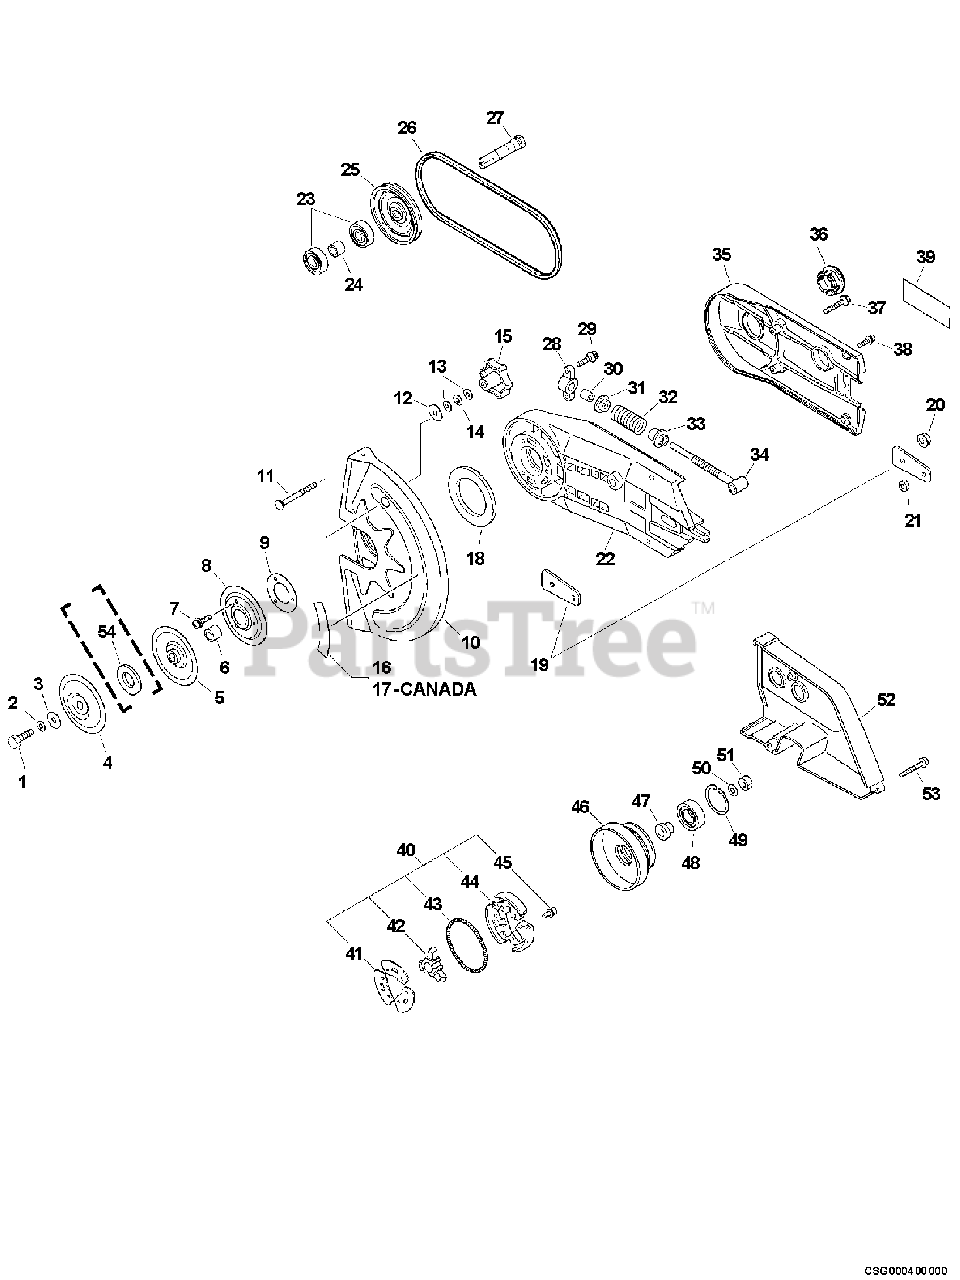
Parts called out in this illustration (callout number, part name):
1	BOLT - 10
2	LOCKWASHER - 10
4	FLANGE, CUTTER
5	FLANGE, CUTTER
7	SCREW - 4X10
8	PLATE, CUTTER COVER
10	COVER, BLADE
11	BOLT - 10X70
13	WASHER - 10
14	LOCKWASHER - 10
16	LABEL - CAUTION
19	SPACER, ARM
20	NUT - FLANGE
21	WASHER - 8
22	COVER, V-BELT
23	BEARING, BALL - 6203
24	SPACER
28	SUPPORT
29	SCREW - 5X20
30	SPACER, SHAFT
31	SEAT, SPRING
32	SPRING, ADJUST
33	ADJUSTER
34	ROD, ADJUST
35	COVER, ARM - FRONT
37	SCREW - 5X25
38	SCREW - 5X20
39	LABEL - ECHO
40	CLUTCH ASSY
41	PLATE, CLUTCH
42	HUB, CLUTCH
43	SPRING, CLUTCH
44	CLUTCH SHOE SET
45	SCREW - 4X6
46	DRUM, CLUTCH
48	BEARING, BALL - 6201
49	RING, RETAINING - 32
50	WASHER, CLUTCH
51	NUT - 8 -- LEFT HAND
52	COVER, ARM
53	SCREW - 5X25
54	WHEEL ADAPTER - 25mm
